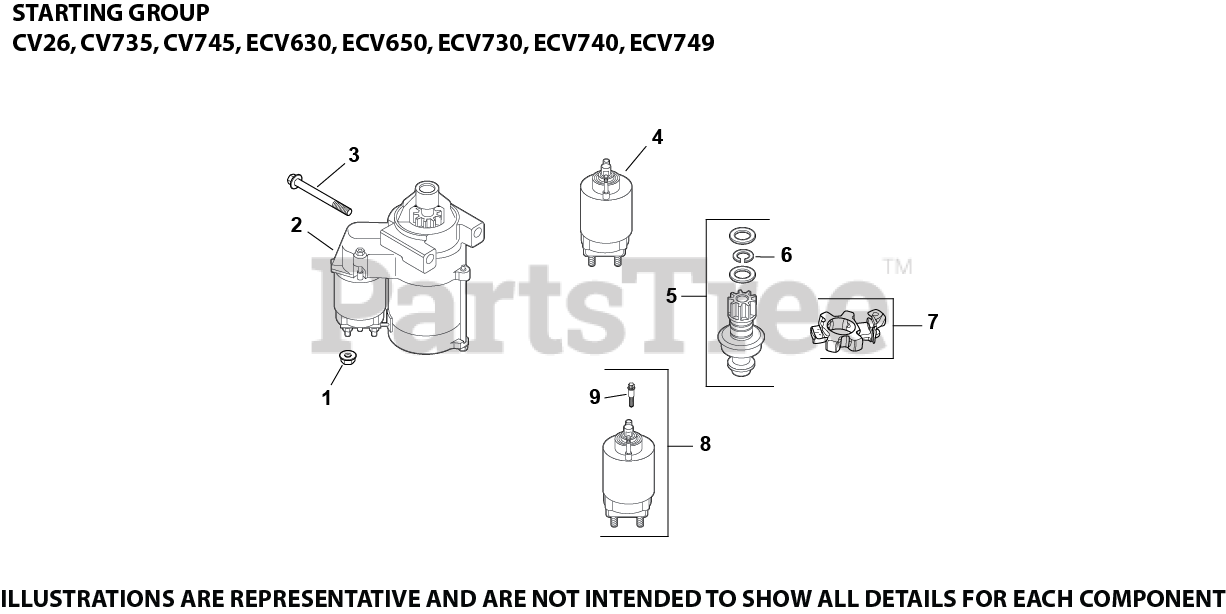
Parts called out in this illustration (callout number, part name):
1	NUT, FLG M8X1.25
2	ELECTRIC STARTER - SOLENOID SHIFT USE 25 098 20-s
3	SCREW, FLG M8X1.25X80
5	KIT, STARTER PINION
6	RING, RETAINING
7	KIT, BRUSH HOLDER
8	KIT, SOLENOID
9	SCREW, EXTERNAL TORX HEAD
